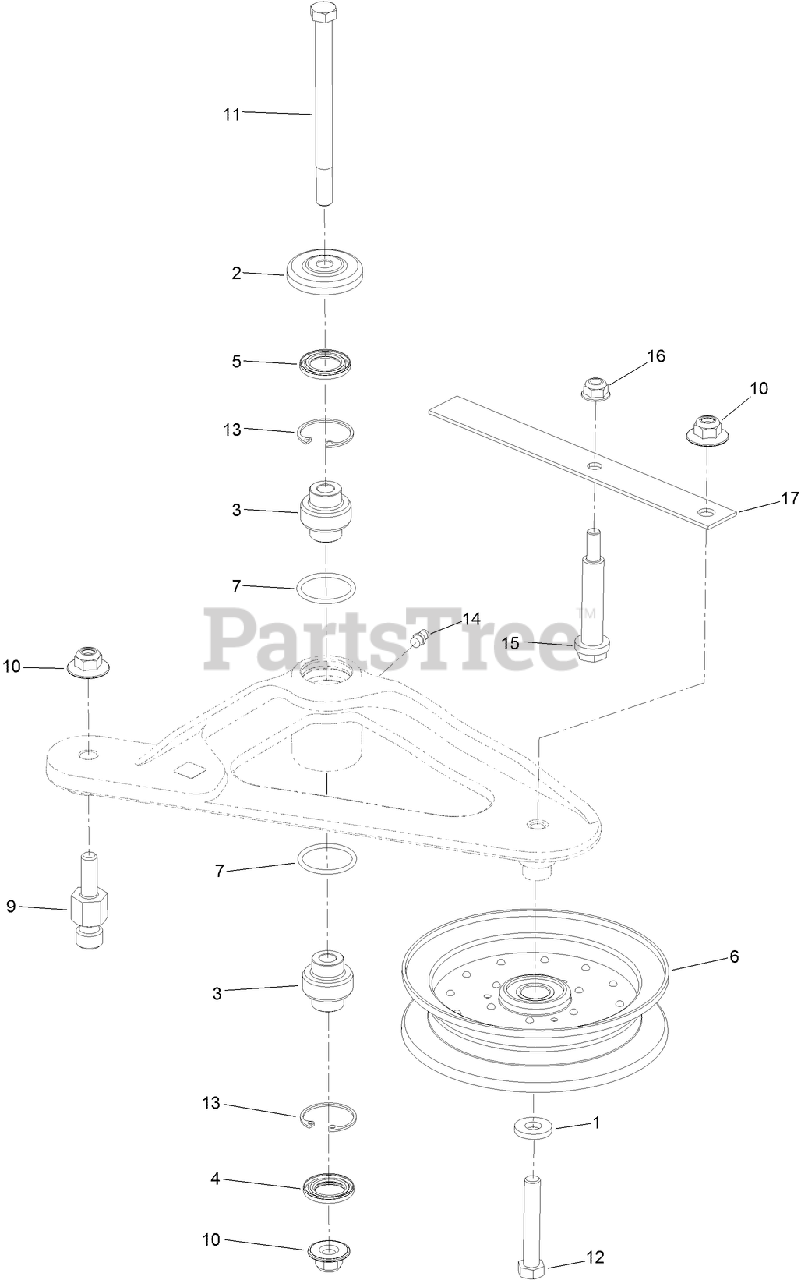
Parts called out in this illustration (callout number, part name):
1	SPACER
2	GUARD-TOP
3	BEARING-SPHERICAL
4	Seal-Lip, Double
5	SEAL-LIP, SINGLE
6	IDLER-PULLEY, FLANGED
7	O-RING
9	PIN-SPRING, ANCHOR
10	NUT-FLANGE, NI
11	SCREW-SHOULDER, HH
12	SCREW-HH
13	RING-SNAP
14	FITTING-GREASE
15	BOLT-SHOULDER
16	NUT-HF, NI
17	SPRING-BELT
